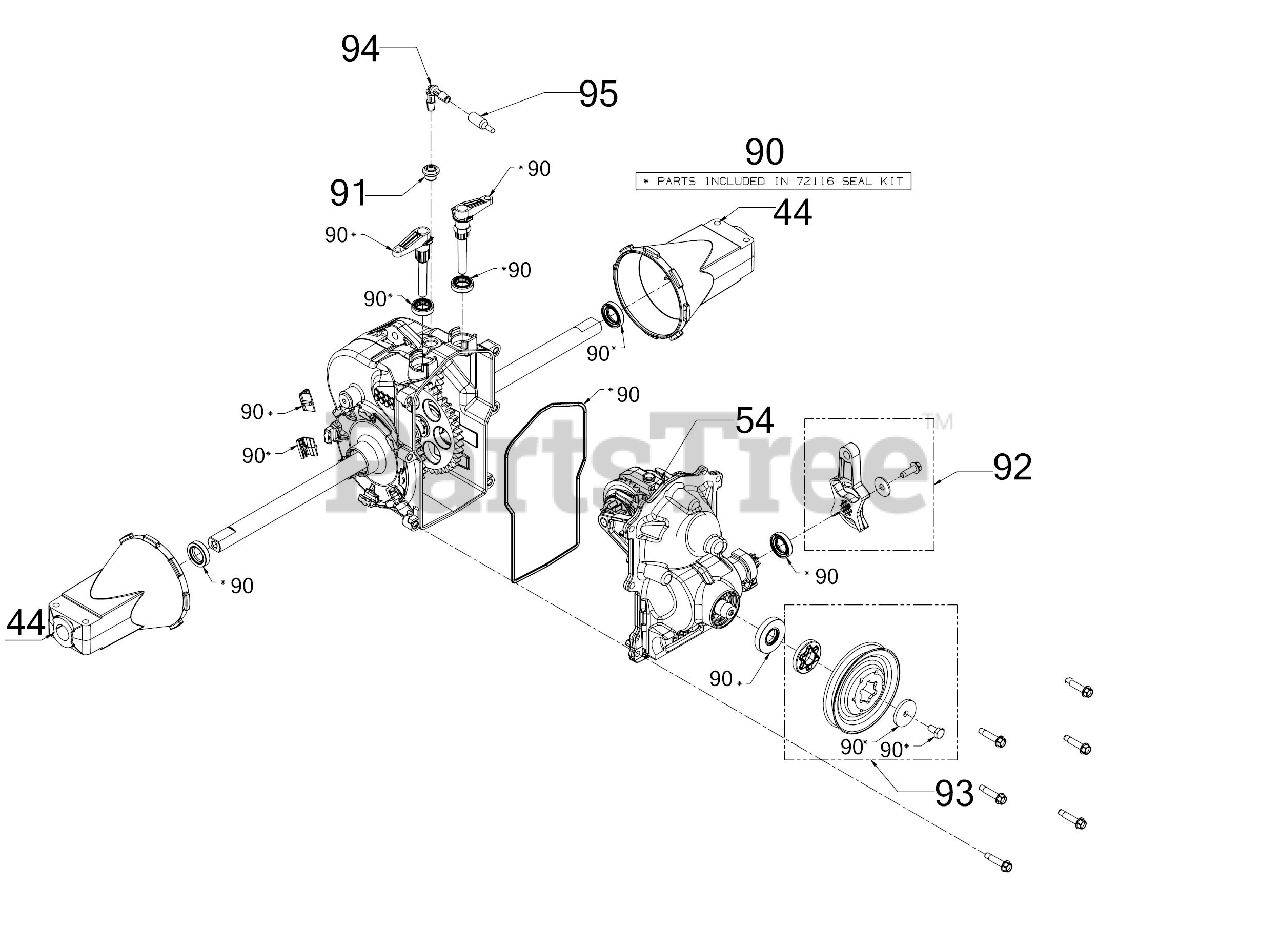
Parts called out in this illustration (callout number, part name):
44	AXLE HORN
54	SCREW 5/16-18X1.5
91	GROMMET-FITTING
92	CONRTOL ARM KIT
93	PULLEY KIT
94	FITTING-ELBOW
95	CAP-FITTING
